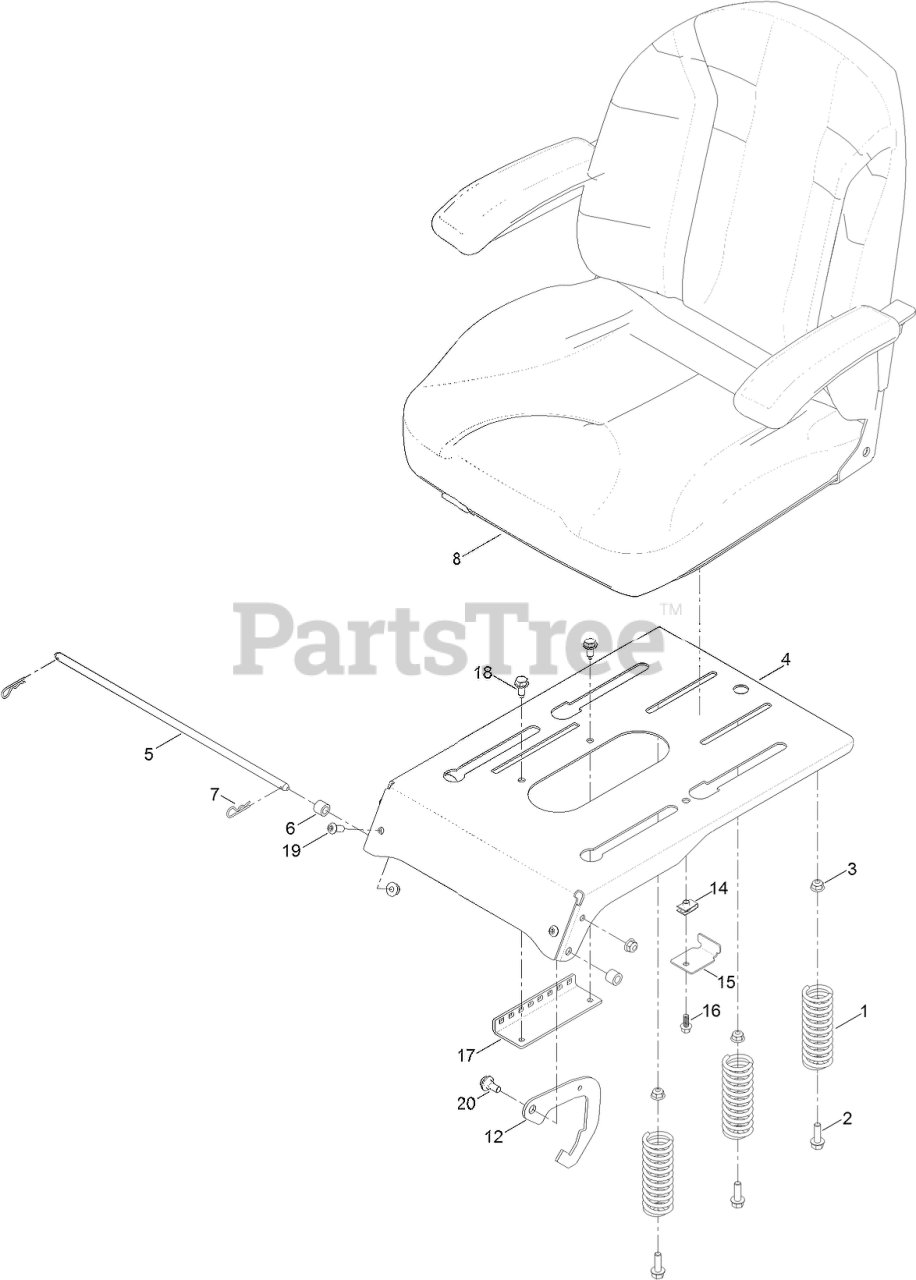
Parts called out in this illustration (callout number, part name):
1	SPRING-COMPRESSION
2	SCREW-HHF
3	NUT-HF, NI
4	PAN-SEAT, DELUXE
5	ROD-STOP
6	BUSHING-LEVER, LIFT
7	PIN-COTTER
8	SEAT ASM
12	LATCH-SEAT
15	BRACKET-STOP, SEAT
16	SCREW-HHF
17	BRACKET-LATCH, SEAT
18	SCREW-HWHTF
19	SCREW-HSBH
20	SCREW-SHOULDER
